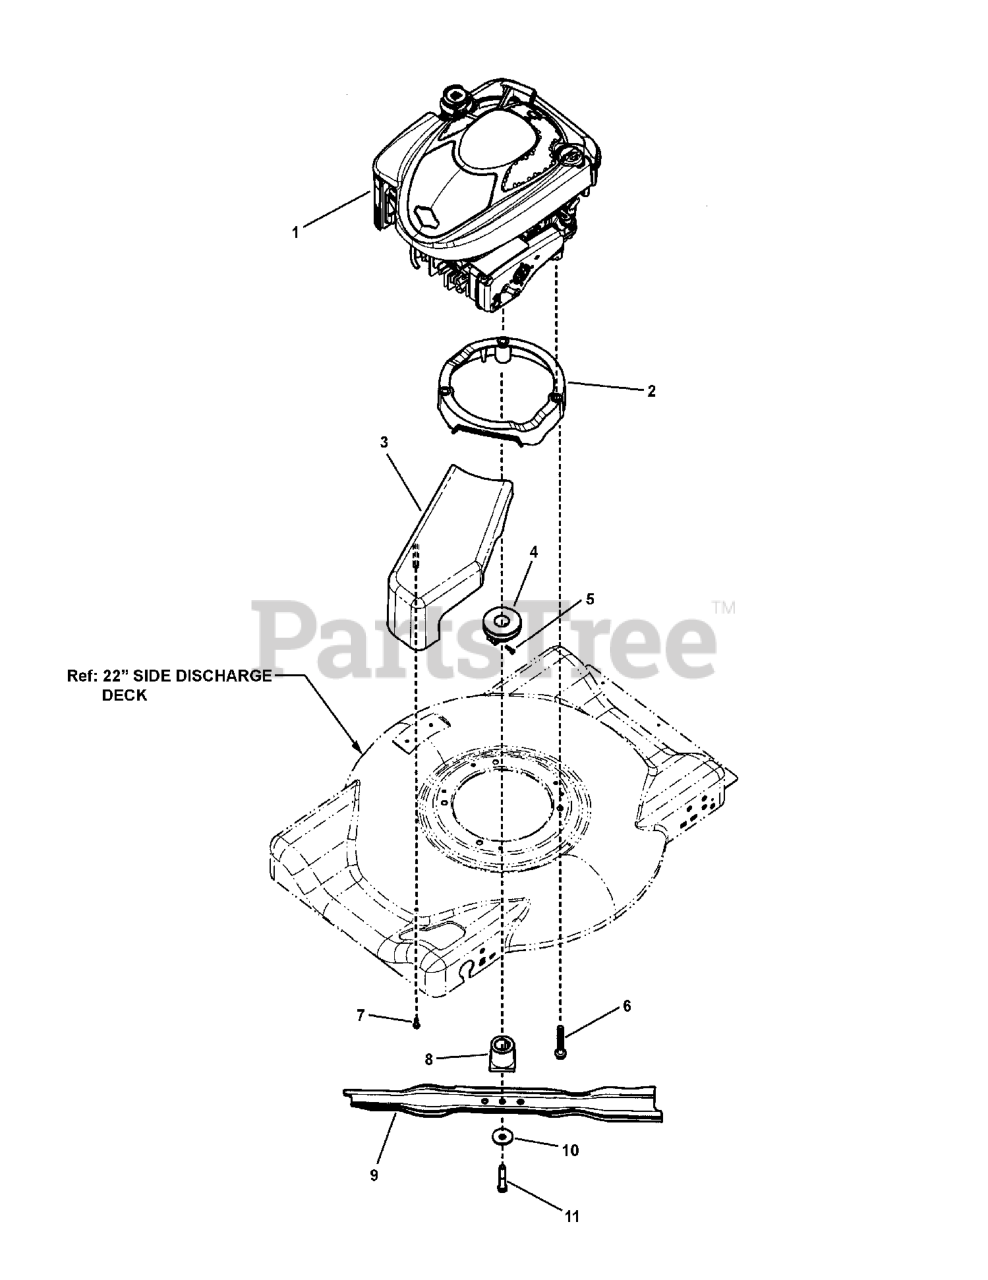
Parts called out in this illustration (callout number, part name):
1	* ENGINE, B&S 625 Series
2	ASSEMBLY, Engine Spacer, 2122FDTM
3	COVER, Belt, 22" Side Discharge, Front Wheel Drive
4	PULLEY, Engine, 22" Deck, Single Speed
5	SCREW, #8-11 x 5/8" Poly Thread
6	BOLT, 3/8-16 x 2-1/2"
7	SCREW, #10-24 x 1.38 Black
8	BLADE HUB, 22" Front Wheel Drive
9	BLADE, Wave, Steel Deck
10	WASHER, Cone
11	SCREW, 3/8-24 x 2" Hex Head Cap, GR 5
